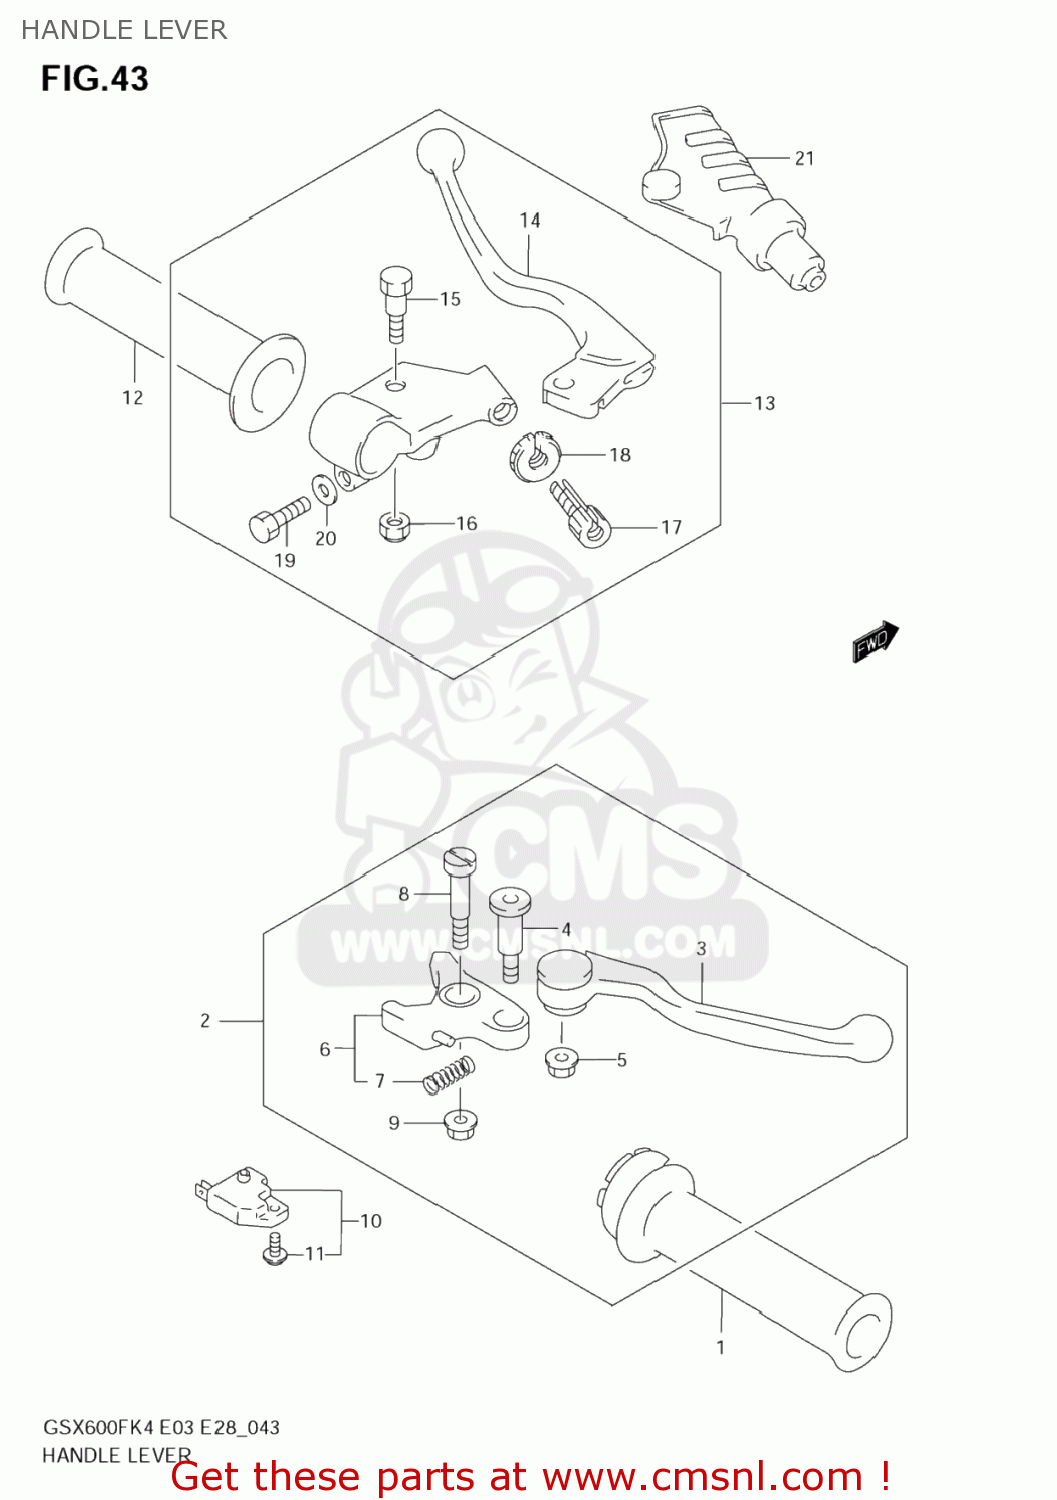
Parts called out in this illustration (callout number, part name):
1	GRIP,THROTTLE
2	LEVER ASSY,BRAKE
3	LEVER,ADJUST
4	BOLT,LEVER
5	NUT
6	RNOCKER
7	SPRING
8	BOLT,LEVER PIVOT
9	NUT
10	SWITCH ASSY,ST
11	SCREW
12	GRIP,LEFT
13	LEVER ASSY,CLUTCH
14	LEVER,CLUTCH
15	BOLT,LEVER SET
16	NUT
17	ADJUSTER,CABLE
18	NUT,CABLE ADJUSTER
19	BOLT
20	WASHER
21	COVER,CLUTCH LEVER
